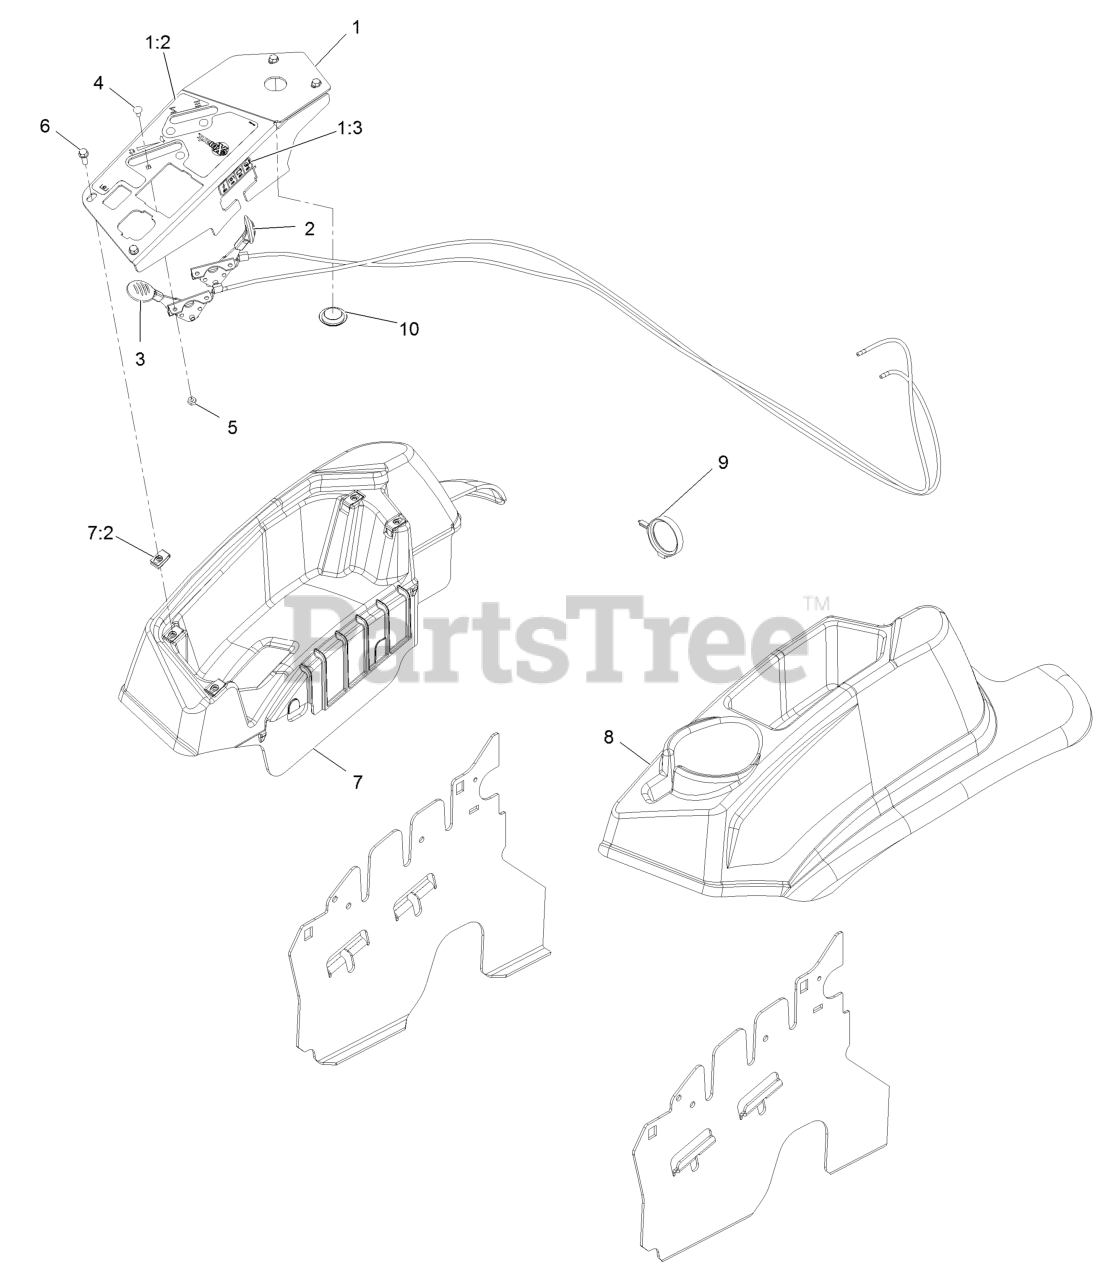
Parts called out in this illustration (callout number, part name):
1	CONSOLE,PANEL W/DECAL
1:2	DECAL-CONTROL PANEL NON-E
1:3	DECAL-FUSES
2	ASM, CHOKE CABLE
3	ASM,THROTTLE CABLE
4	BOLT-CARR
5	NUT-LOCK, NI
6	SCREW-HWH
7	CONSOLE,RH AS ASM
7:2	Nut-Retainer-Panel 1/4-20
8	CONSOLE, LH AS
9	CLAMP-HARNESS
10	PLUG-PLASTIC
